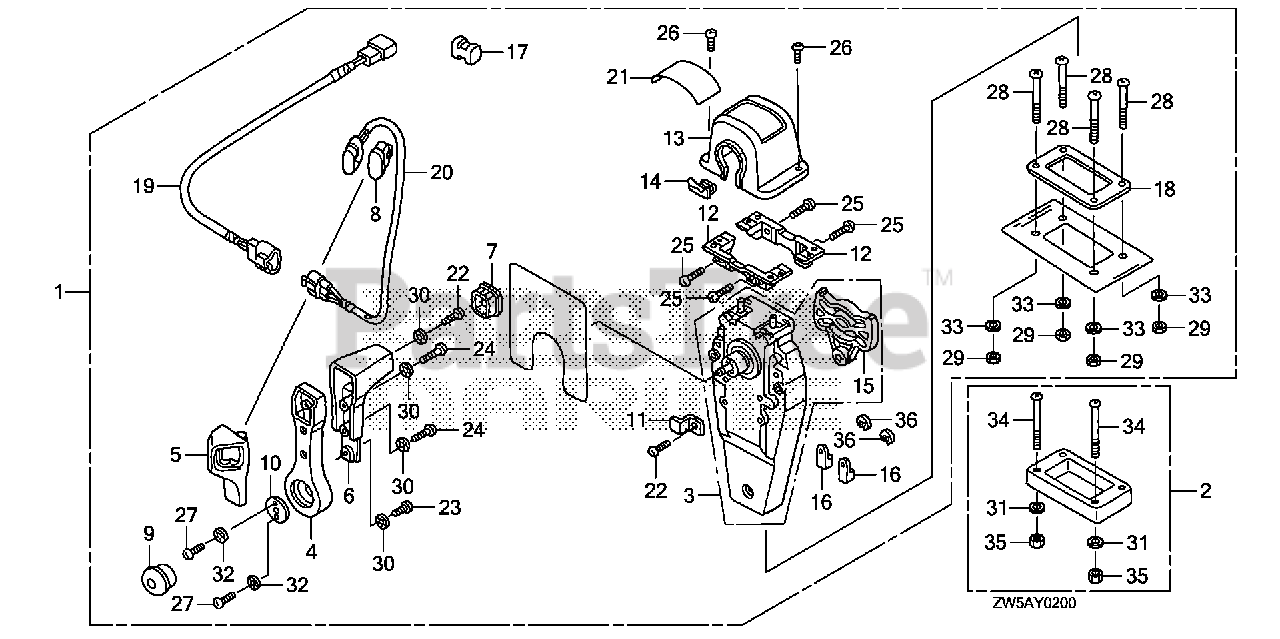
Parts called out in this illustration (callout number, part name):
1	BOX KIT, REMOTE CONTROL (TOP MOUNT SINGLE)(R)
2	SPACER KIT, REMOTE CONTROL BOX (TOP MOUNT SINGLE)
3	HOUSING ASSY., L. (INNER) (TOP MOUNT)
4	HANDLE, REMOTE CONTROL
5	COVER, L. GRIP
6	GRIP, REMOTE CONTROL HANDLE
7	CAP, GRIP
8	CAP, SWITCH
9	BUTTON, THROTTLE
10	PLATE, HANDLE
11	PLATE, CABLE CLAMP
12	BRACKET, REMOTE CONTROL HOUSING
13	HOUSING, REMOTE CONTROL BOX
14	HOUSING, LEAD
15	PLATE, DWELL
16	TERMINAL, CABLE
17	SPACER, CABLE CLAMP
18	GASKET, SINGLE
19	SUB-HARNESS ASSY., POWER TRIM-TILT (A)
20	SWITCH ASSY., POWER TRIM-TILT (A)
21	MARK, REMOTE CONTROL (SINGLE)
22	SCREW, PAN (5X16)
23	SCREW, PAN (5X10)
24	SCREW, PAN (5X20)
25	SCREW, PAN (5X18)
26	SCREW, PAN (4X10)
27	SCREW, PAN (6X18)
28	SCREW, PAN (5X40)
29	NUT, HEX. (5MM)
30	WASHER, LOCK (5MM)
31	WASHER, PLAIN (5MM)
32	WASHER, LOCK (6MM)
33	WASHER, PLAIN (5MM)
34	SCREW, PAN (5X65)
35	NUT, HEX. (5MM)
36	E-RING (6MM)
